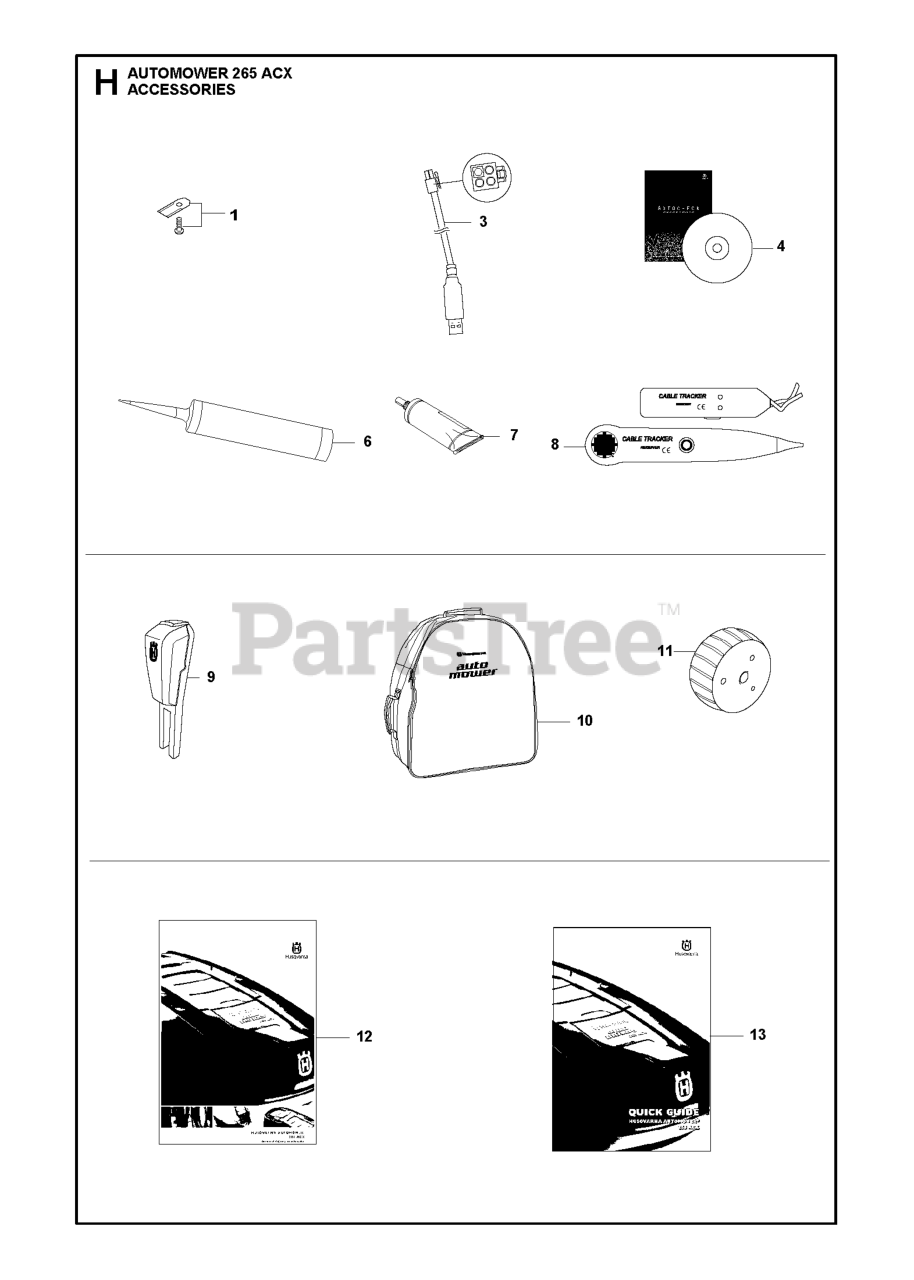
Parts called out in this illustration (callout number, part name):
1	HUS BLADE SET 45 PCS
1	HUS BLADE SET 300 PCS
1	HUS BLADE SET 9 PCS
3	USB SERVICE CABLE
4	DVD AUTOCHECK EXP SERVICE
6	GREASE 300 ML
7	GREASE OKS 110 85ML
8	TEST EQUIPMENT
9	SIGNAL BOOSTER
11	HEAVY FRONT WHEEL KIT INCL PAC
11	WHEEL ASSY
